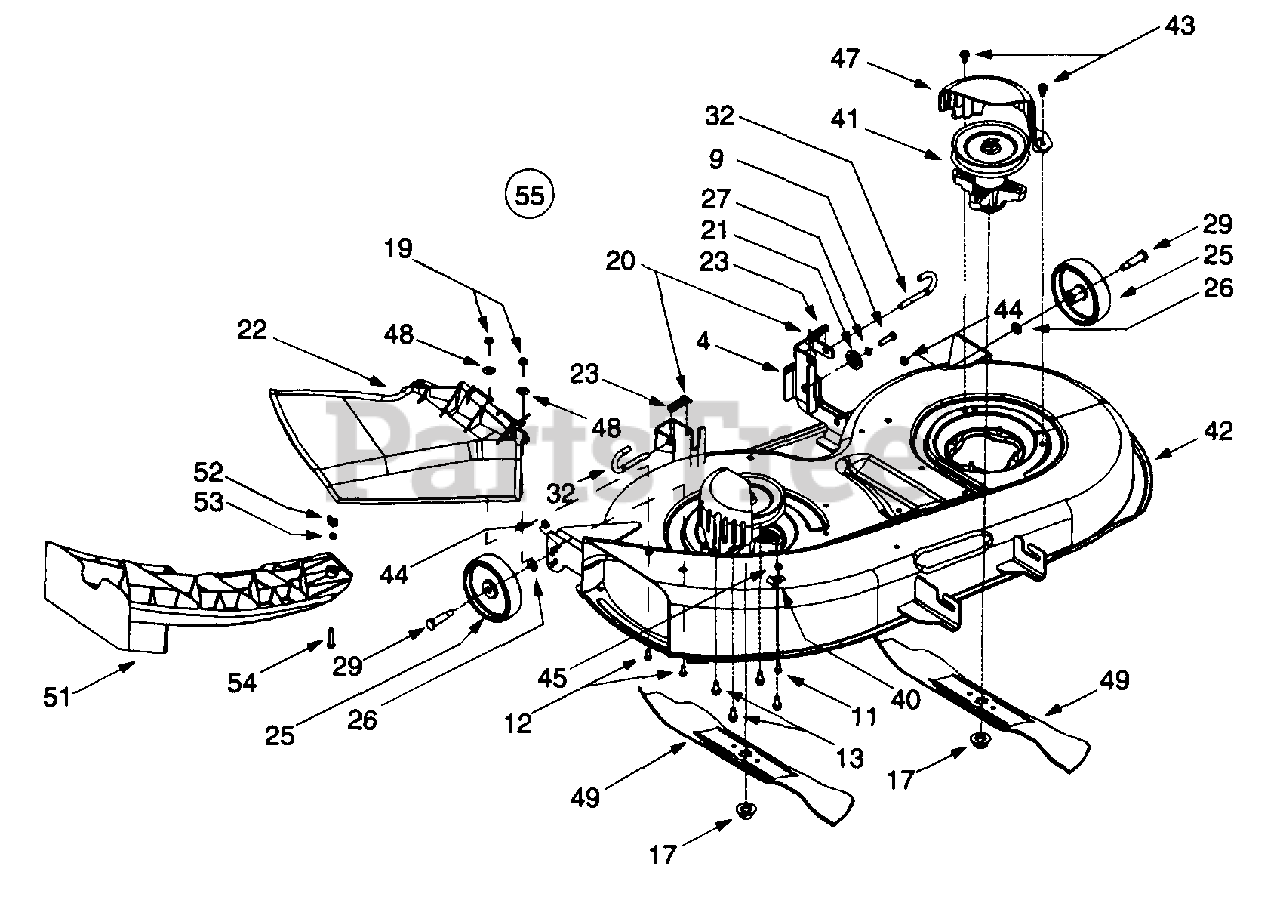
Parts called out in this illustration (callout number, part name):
9	Hex Cap Screw, 5/16-18 x 1.25
11	Self Tapping Screw, 5/16-18 x .875
12	Hex Cap Screw, 1/4-20 x .62
13	Self Tapping Screw, 5/16-18 x .75
17	Hex Flange Nut, 5/8-18
19	Hex Flange Lock Nut, 1/4-20
20	Internal Cotter Pin, .072 x 1.12
21	Deck Adjustment Gear
22	Side Discharge Chute Assembly
23	Compression Spring, .406 x .531 x 1.75
25	Deck Wheel, 5 x 1.38
26	Bell Washer, .401 x .87 x .063
27	Lock Washer, 5/16
29	Shoulder Spacer, .498 x 1.53
32	Deck Release Pin
40	Retainer Hook
41	Spindle Assembly w/ Fitting, 5.75 Dia
43	Self Tapping Screw, 5/16-18 x .625
44	Top Lock Jam Nut, 3/8-16
45	Hex Sems Nut, 1/4-20
47	Belt Cover
48	Bell Washer, .265 x .75 x .062
49	Three-in-one Blade, Star Center, 21.23
51	Mulch Plug, 42-inch Decks
52	Wing Nut, 1/4-20
53	Center Lock Nut, 1/4-20
54	Hex Cap Screw, 1/4-20 x 1.25
